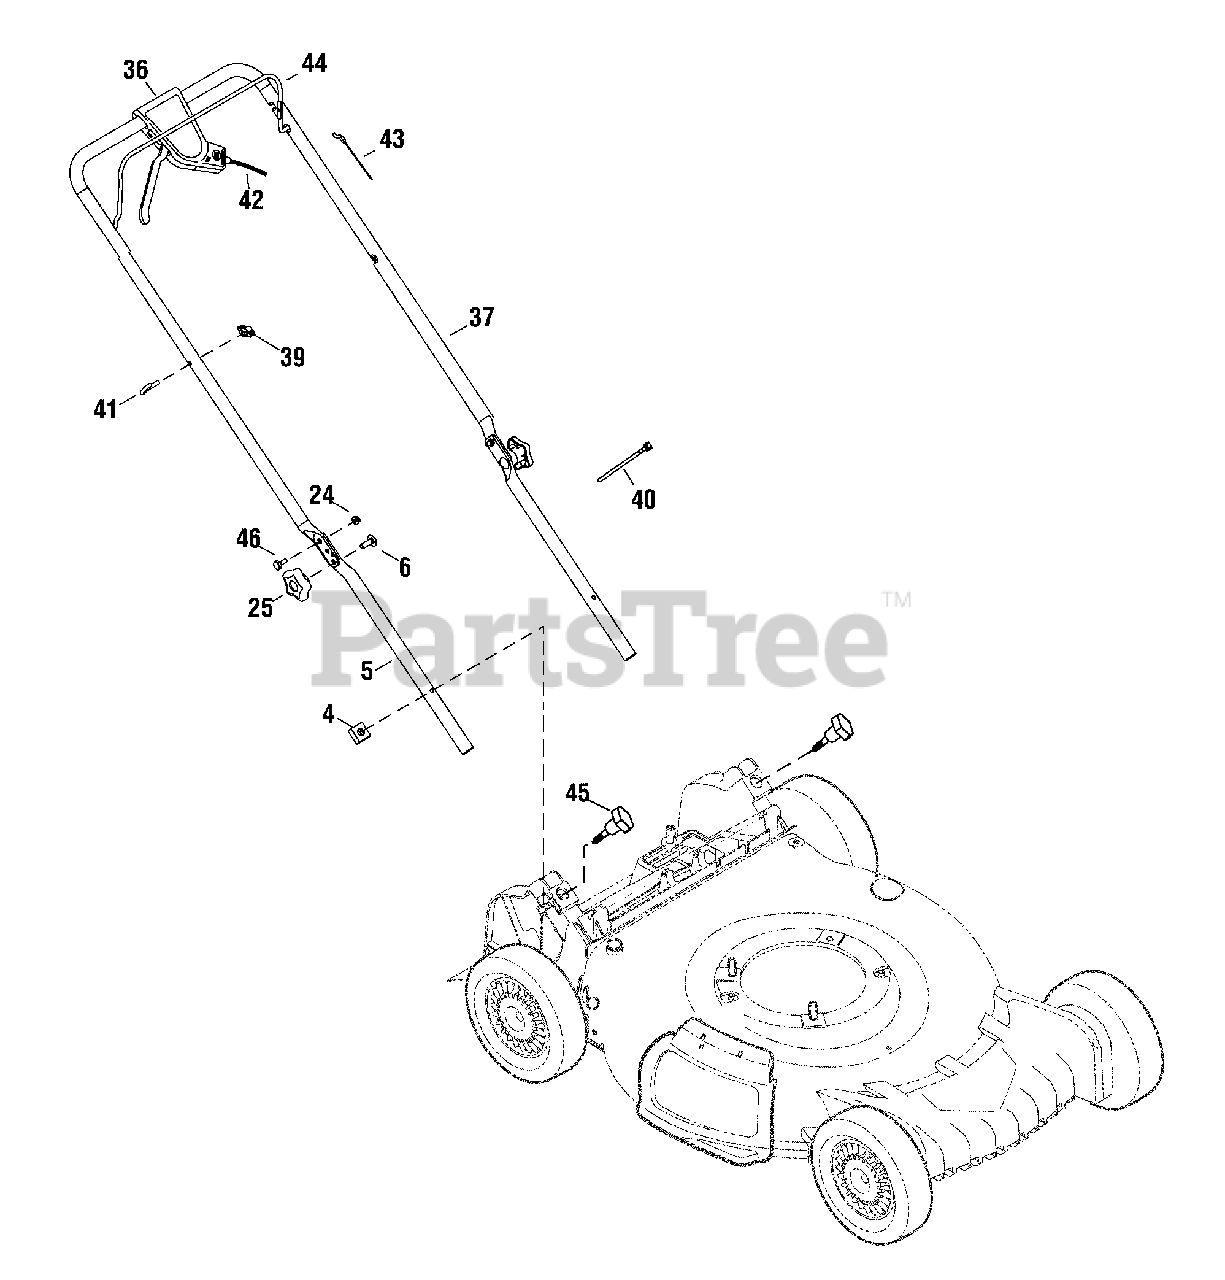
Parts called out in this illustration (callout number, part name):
4	NUT, Square, 1/4-20
5	HANDLE, Lower
6	BOLT, Carriage, 5/16-18 x 1, GR5
24	NUT, Nylock Flanged, 1/4-20
25	KNOB, Wing, 5/16-18
36	ASSEMBLY, Control Lever
37	HANDLE, Upper
39	KNOB, 1/4-20
40	TIE, Self Lock
41	GUIDE, Rope
42	CABLE, Control, Variable Speed
43	CABLE, OPC Engine Brake
44	BAIL, Blade Control
45	NUT, Wing
46	BOLT, Shoulder, 1/4-20
